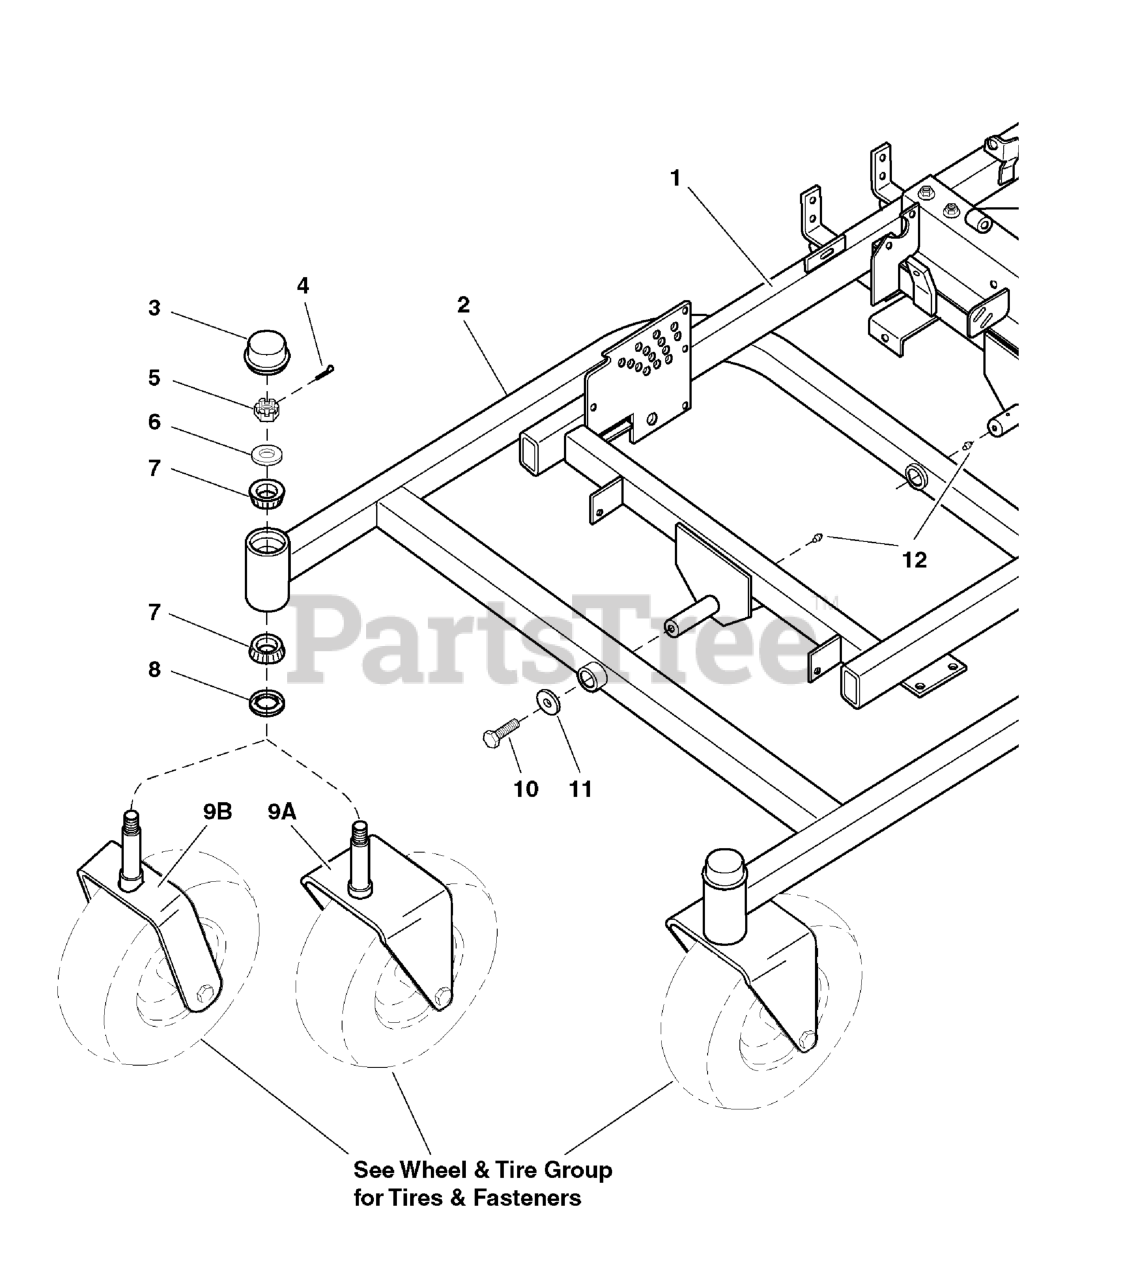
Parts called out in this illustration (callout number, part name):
1	MAIN FRAME
2	FRAME, Front Pivot
3	CAP
4	PIN, COTTER, 1/8 X 1-1/4
5	NUT, 3/4-16 Hex Slotted
6	WASHER, 3/4 SAE
7	BEARING, Tapered Roller
8	SEAL, GREASE
9A	YOKE, Caster
9B	CASTER YOKE
10	BOLT, 1/2-20 X 1-1/4" GD5 CZ
11	WASHER, Frame Retaining
12	GREASE FITTING
